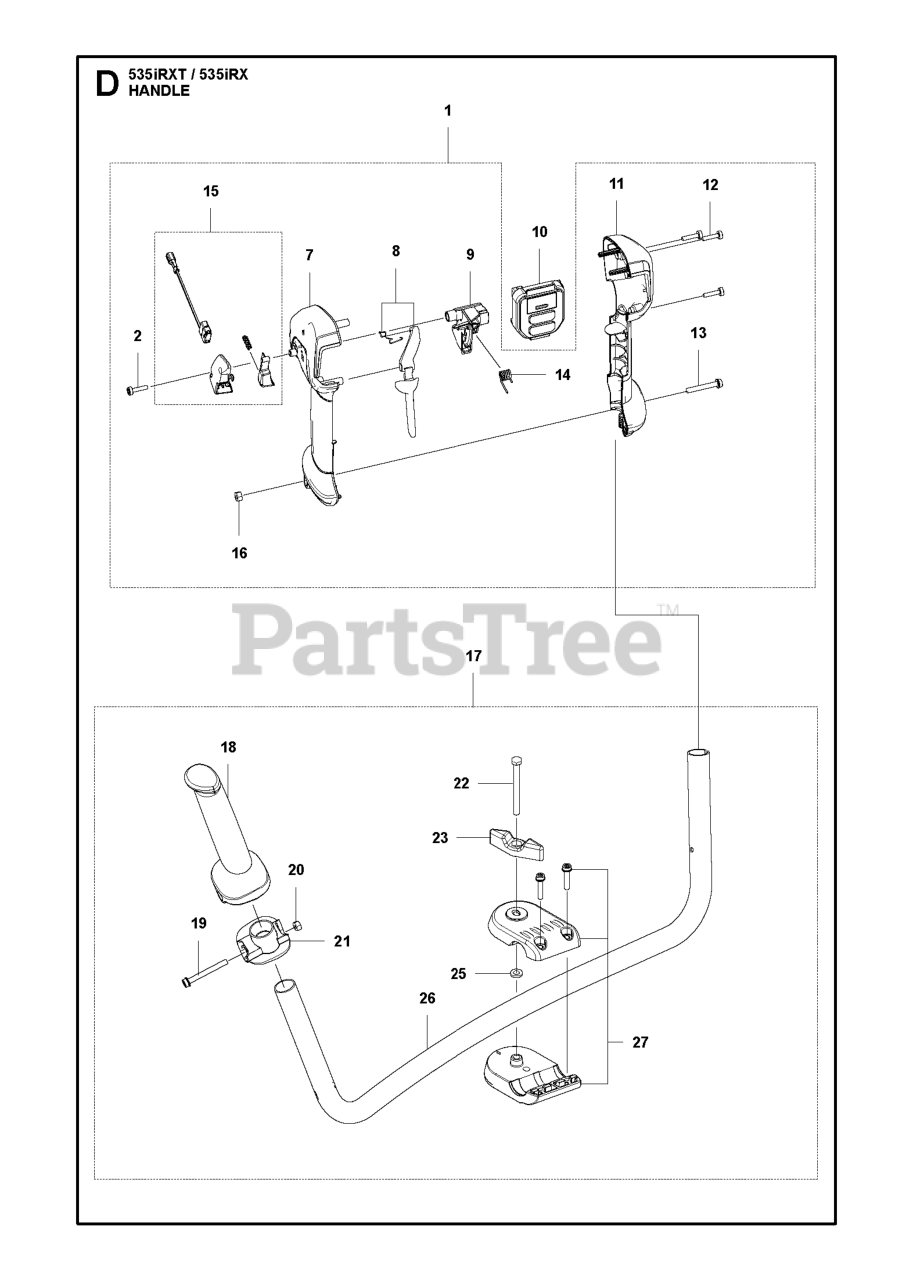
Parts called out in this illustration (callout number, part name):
1	HANDLES
2	SCREW ITXSCT PW4.2X18 10.9 ZN
7	Handles
7	HANDLE HALF LEFT
9	THROTTLE CONTROL ASSY
10	Controls
10	CONTROL PANELS
11	HANDLE HALF RIGHT
12	SCREW ITXSCT PW4.2X18 10.9 ZN
14	SPRING THROTTLE CONTROL
15	BUTTONS
19	SCREWS
